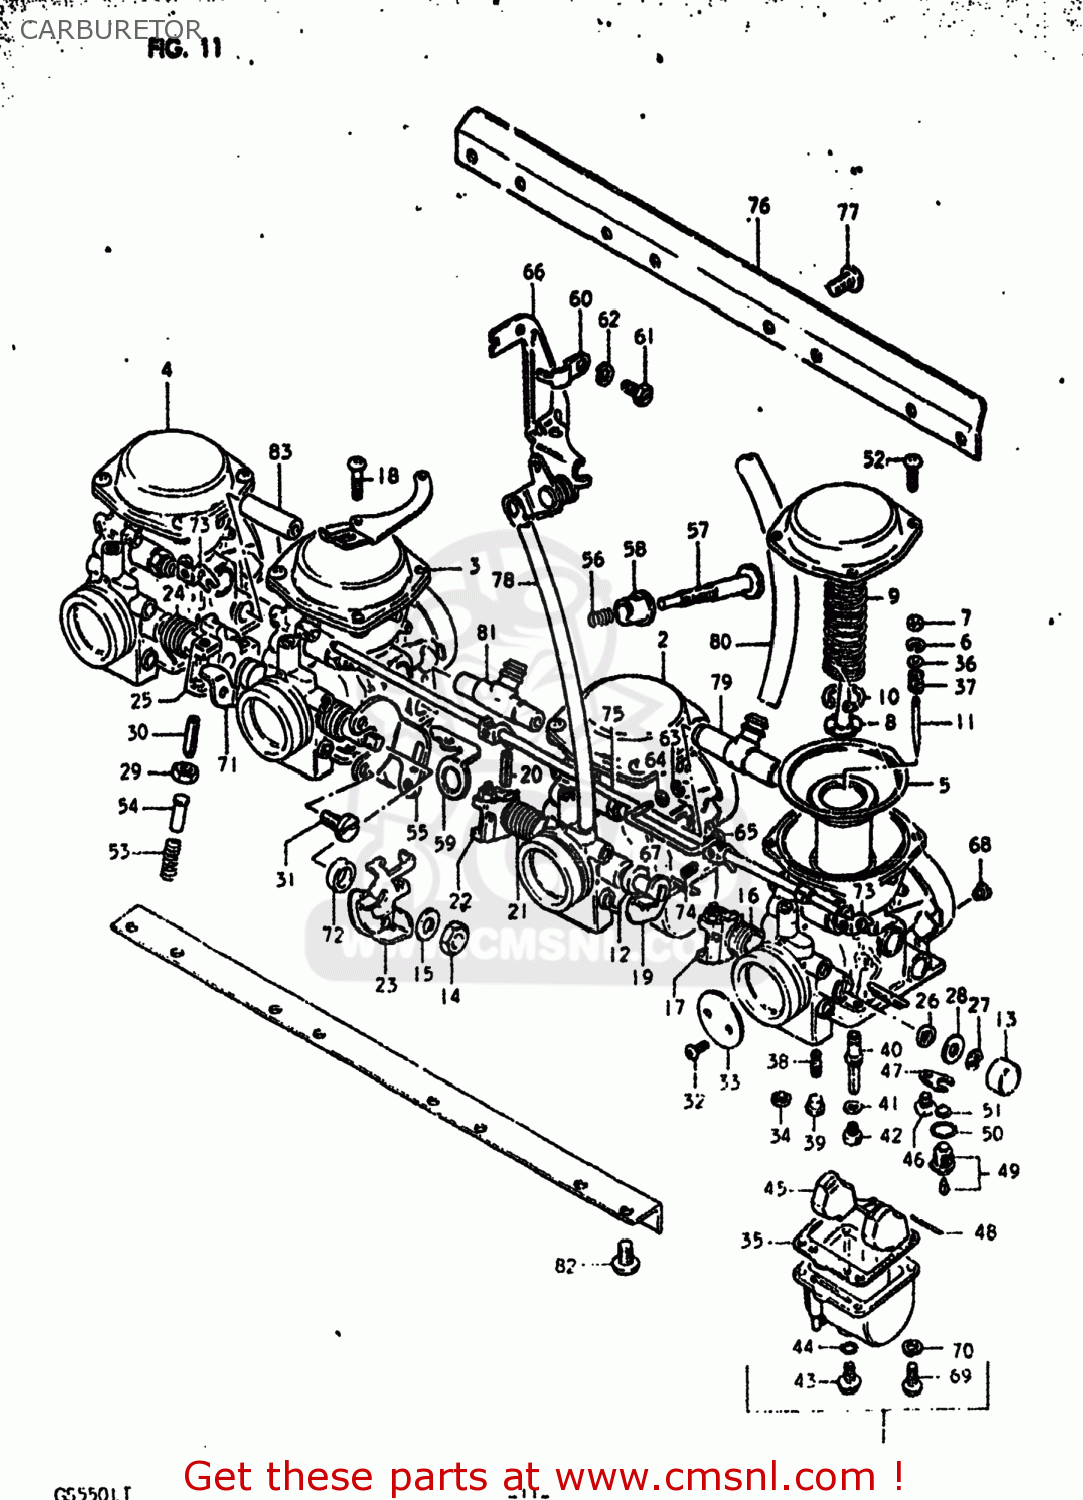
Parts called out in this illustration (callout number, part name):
1	CARBURETOR ASSEMBLY,NO.1 (A
2	CARBURETOR ASSEMBLY
3	CARBURETOR ASSEMBLY
4	CARBURETOR ASSEMBLY
5	DIAPHRAGM ASSEMBLY
6	CLIP,NEEDLE
7	RING
8	HOLDER,GUIDE
9	SPRING
10	E RING
11	NEEDLE JET
12	GASKET,THROTTLE SHAFT (NAS)
13	CAP
14	NUT
15	SCREW
16	SPRING,THROTTLE SHAFT
17	SHAFT,THROTTLE
18	SCREW
19	SHAFT,THROTTLE
20	PIN,THROTTLE SHAFT
21	SPRING,THROTTLE SHAFT
22	LEVER,THROTTLE SHAFT
23	LEVER ASSEMBLY,THROTTLE
24	SPRING,THROTTLE SHAFT
25	SHAFT,THROTTLE
26	SEAL
27	E RING
28	GASKET,THROTTLE SHAFT (NAS)
29	NUT
30	SCREW
31	SCREW,THROTTLE ADJUST B
32	SCREW
33	VALVE,THROTTLE
34	GASKET (NAS)
35	GASKET,FLOAT CHAMBER (NAS)
36	WASHER
37	SPRING
38	JET,PILOT
39	PLUG,NEEDLE JET
40	JET,NEEDLE
41	WASHER,NEEDLE NOZZLE
42	JET,MAIN(92.5)
43	PLUG,DRAIN
44	GASKET (NAS)
45	FLOAT
46	SCREW
47	PLATE
48	PIN,FLOAT
49	VALVE ASSEMBLY,NEEDLE
50	O-RING,NEEDLE VALVE
51	FILTER
52	SCREW
53	SPRING,THROTTLE SCREW
54	PIN,THROTTLE LEVER
55	BRACKET,THROTTLE ADJUST
56	SPRING
57	SCREW
58	BUSH
59	BRACKET,THROTTLE ADJUST
60	BRACKET,STARTER
61	BOLT
62	LOCK WASHER
63	CAP,LEVER
64	SEAT,SPRING
65	LEVER ASSY
66	BRACKET
67	ROD,STARTER LEVER
68	JET,AIR(150)
69	SCREW
70	LOCK WASHER
71	SHAFT,THROTTLE
72	WASHER
73	LEVER
74	SCREW
75	SHAFT,STARTER
76	BRACKET
77	SCREW
78	HOSE
79	NIPPLE
80	HOSE
81	NIPPLE,CARBURETOR
82	SCREW 6X12
83	NIPPLE
